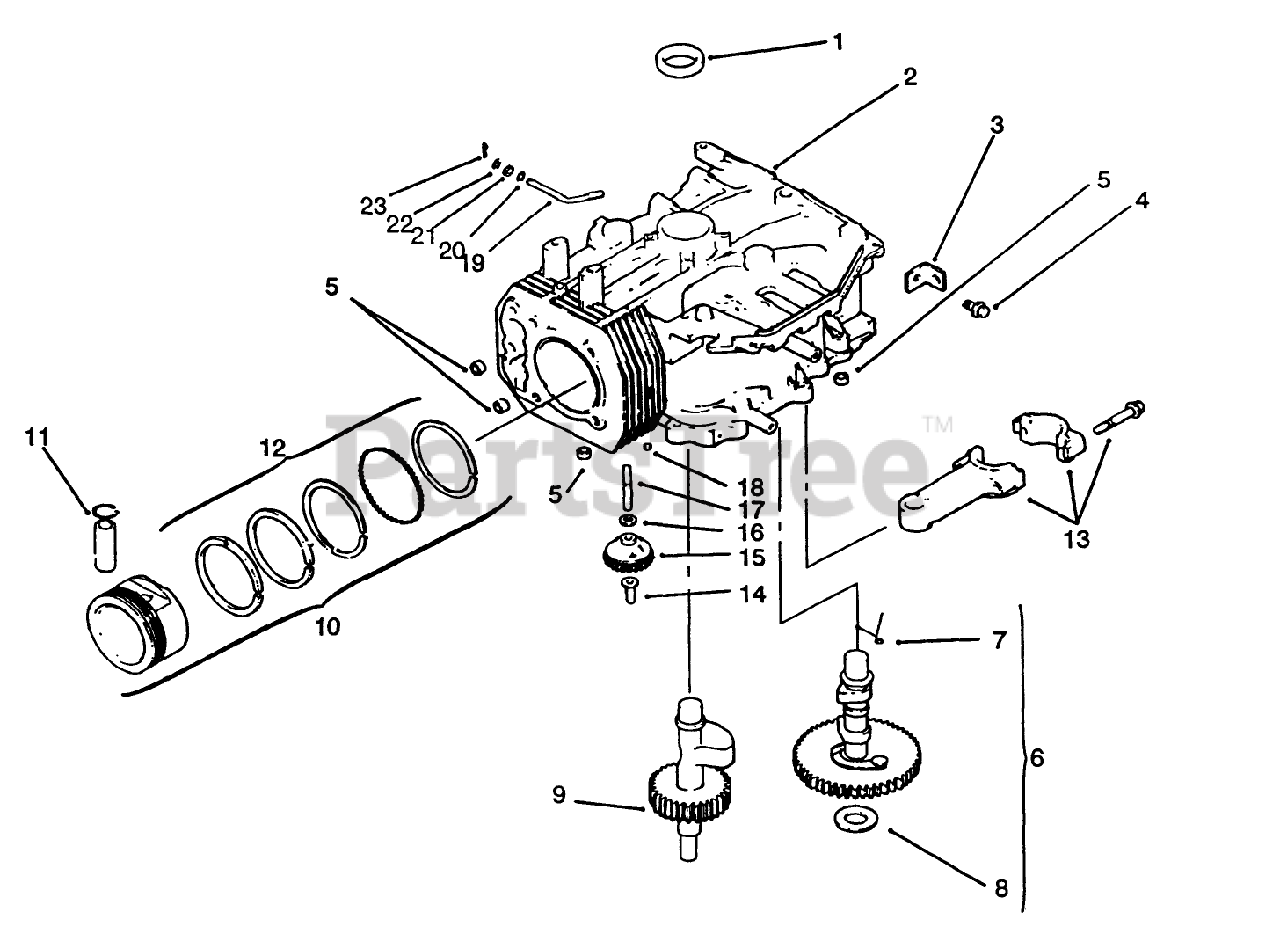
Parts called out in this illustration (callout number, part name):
1	Seal-Crankshaft (Only On: 72042, 72043, 72062, 72063)
3	Strap-Lifting (Only On: 72042,72043,72062,72063)
4	Screw M8x1.25x22 (Only On: 72042, 72043, 72062, 72063)
5	Pin-Dowel
6	Kit-Camshaft INC 7-8 (Only On: 72042, 72063, 72062, 72043)
7	Spring-Actuating (Only On: 72042,72043,72062,72063)
8	Shim-Camshaft
9	Shaft-Balance (Only On: 72042, 72043, 72062, 72063)
10	Piston ASM STD INC 11-12 (Only On: 72042, 72063, 72062, 72043)
10	Piston ASM .25 INCL 11-12 (Only On: 72042,72043,72062, 72063)
10	Piston ASM .50 INCL 11-12 (Only On: 72042, 72043, 72062, 72063)
11	Retainer-Piston Pin (Only On: 72042, 72043,72062,72063)
12	Ring Set STD (Only On: 72042,72043,72062,72063)
12	Ring Set .25 (Only On: 72042,72043,72062,72063)
12	Ring Set .50 (Only On: 72042,72043,72062,72063)
13	Connecting Rod STD (Only On: 72042, 72063, 72062, 72043)
13	Connecting Rod .25 (Only On: 72042, 72063, 72062, 72043)
14	Pin-Governor
15	Gear-Governor ASM (Only On: 72042, 72063, 72062, 72043)
17	Shaft-Govenor Gear
19	Shaft-Governor Cross (Only On: 72042, 72063, 72062, 72043)
20	Washer-Governor Shaft (Only On: 72042, 72063, 72062, 72043)
21	Seal
22	Washer-Flat (Only On: 72042, 72063, 72062, 72043)
23	Pin-Hitch
